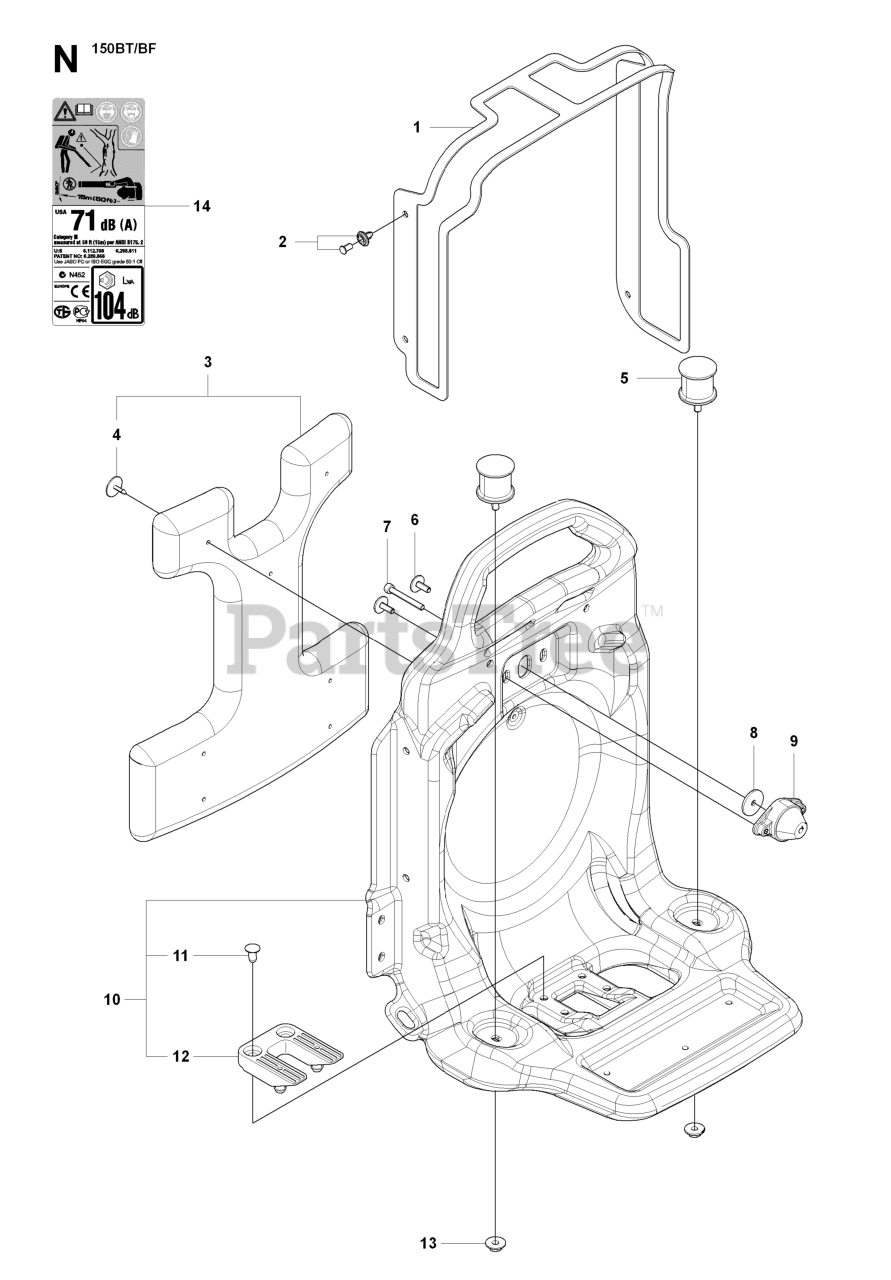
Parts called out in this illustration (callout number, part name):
2	CLIP
3	PAD COMP
4	CLIP
5	DAMPER
7	BOLT
8	WASHER
9	DAMPER
11	CLIP
13	NUT (M6)
